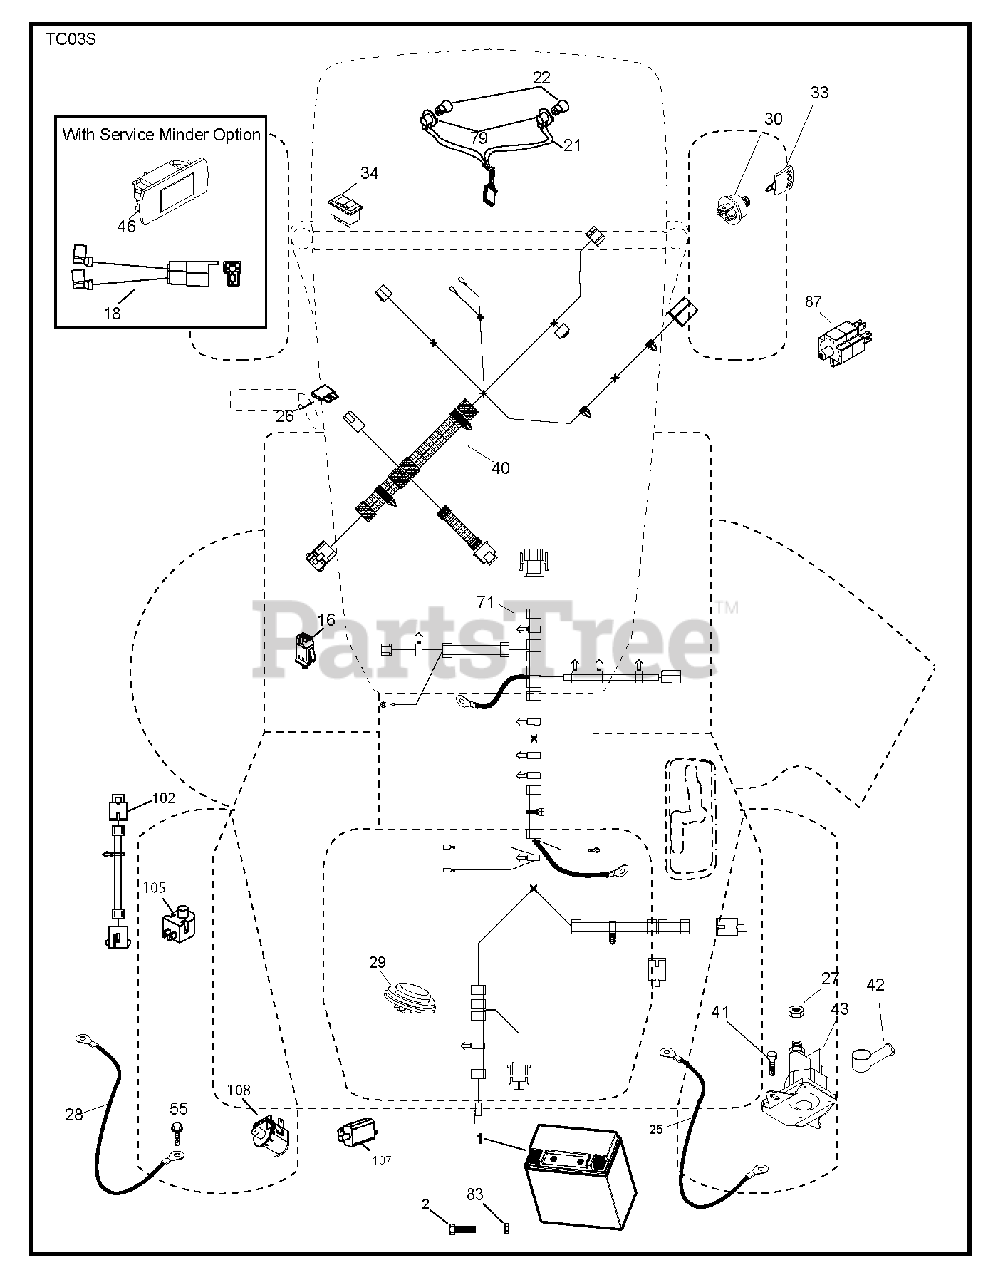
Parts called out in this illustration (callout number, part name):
2	SCREW.HEX.HEAD.CAP.M6 X1.12W
16	SWITCH INTERLOOK PUSH-IN
21	HARNESS ASSY LIGHT
25	CABLE BATTERY CABLE
27	NUT
29	SWITCH.SEAT.DELTA.OPC.
30	SWITCH.IGN.DELTA.W.LGH.ROS
33	KEY.CHAIN.BLISTER.PACK.GEN.INT
40	HARNESS.ELECTRICAL.DASH.SRD
41	SCREW
42	TERMINAL COVER
43	SOLENOID.W/BRASS.PLUNG
46	GUAGE.SRVCMNDR.HRMTR.
55	SCREW 5/16"
71	HARNESS
79	BULB HOLDER ASM.
83	Square Nut, M6 X 8.5 X 11mm
87	Railmount Switch, No-Nc-Nc
102	HARNESS ASSY
105	REVERSE SWITCH
108	SWITCH.SNAPMOUNT.NC
